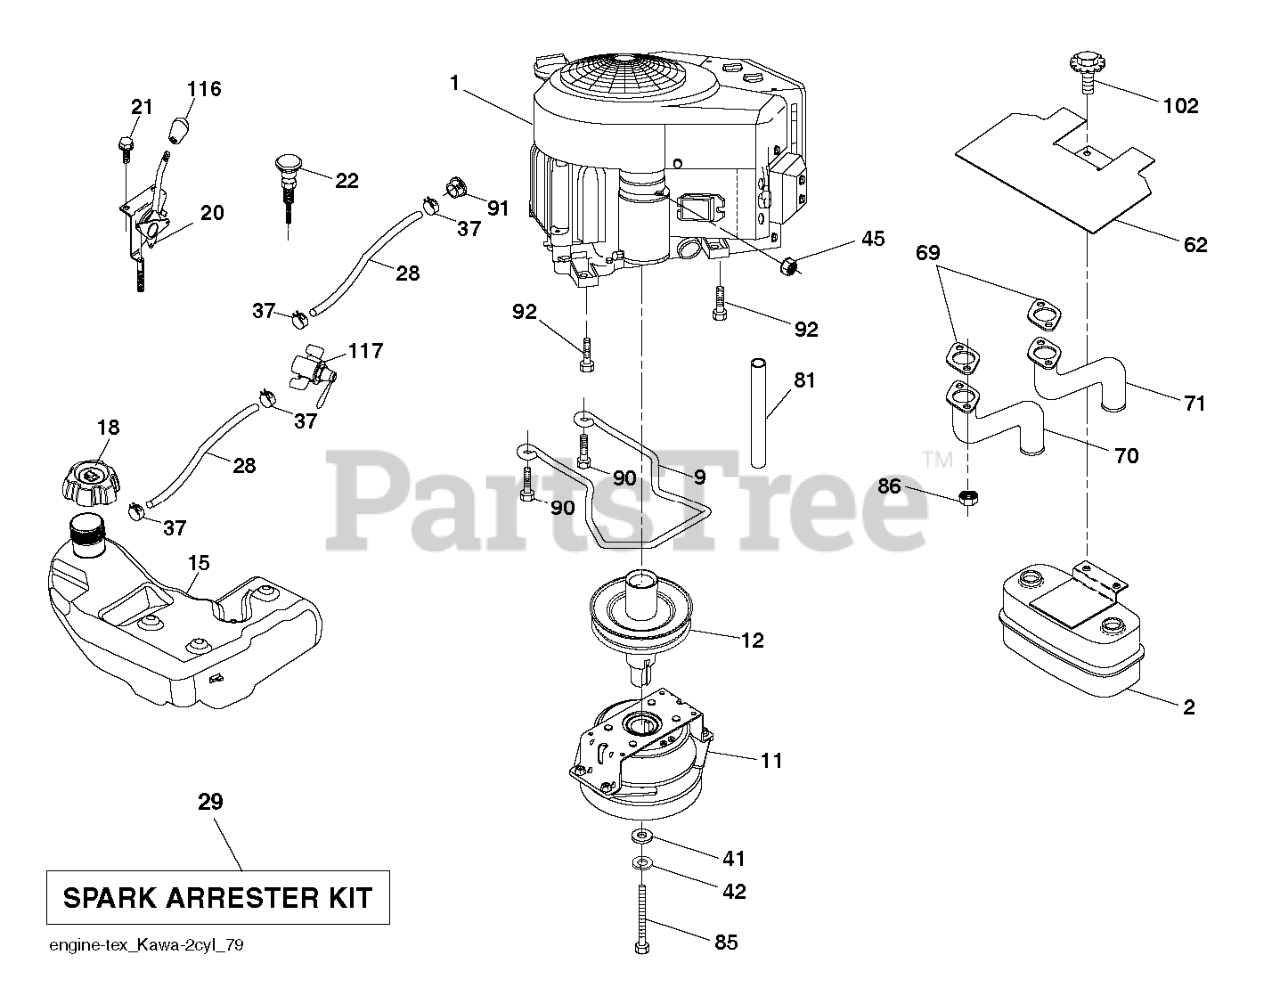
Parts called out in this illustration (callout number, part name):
2	MUFFLER.ASM.TWIN.MNTG.BRACKET
9	KEEPER.BELT.ENG.4.25"2.BLT.431
11	CLUTCH.OGURA.5.0PD.GT1.5A-EH01
12	PULLEY ENGINE
15	Tanks
18	CAP ASSY FUEL 3" GRAY
20	CONTROL.THROTTLE.PRO.
22	CONTROL, CHOKE
28	LINE.FUEL.64"REAR.EMIS
29	KIT.SPARK ARRESTOR 794945 B&S
37	HOSE CLAMP
62	SHIELD.HEAT.MUFFLER
70	TUBE.EXHAUST.LH.FR961/FR730
71	TUBE.EXHAUST.RH.FR961/FR730
81	TUBE, DRAIN OIL ASM.
85	BOLT.HEX.7/16-20X3.GR5.YELLOW
86	NUT.HEX.FLANGE.TOPLOCK
90	SCREW 3/8-16X1
91	BUSHING.1.375OD
92	SCREW 3/8-16X1
102	SCREW
116	KNOB - SHIFT
117	VALVE FUEL RESERVE
